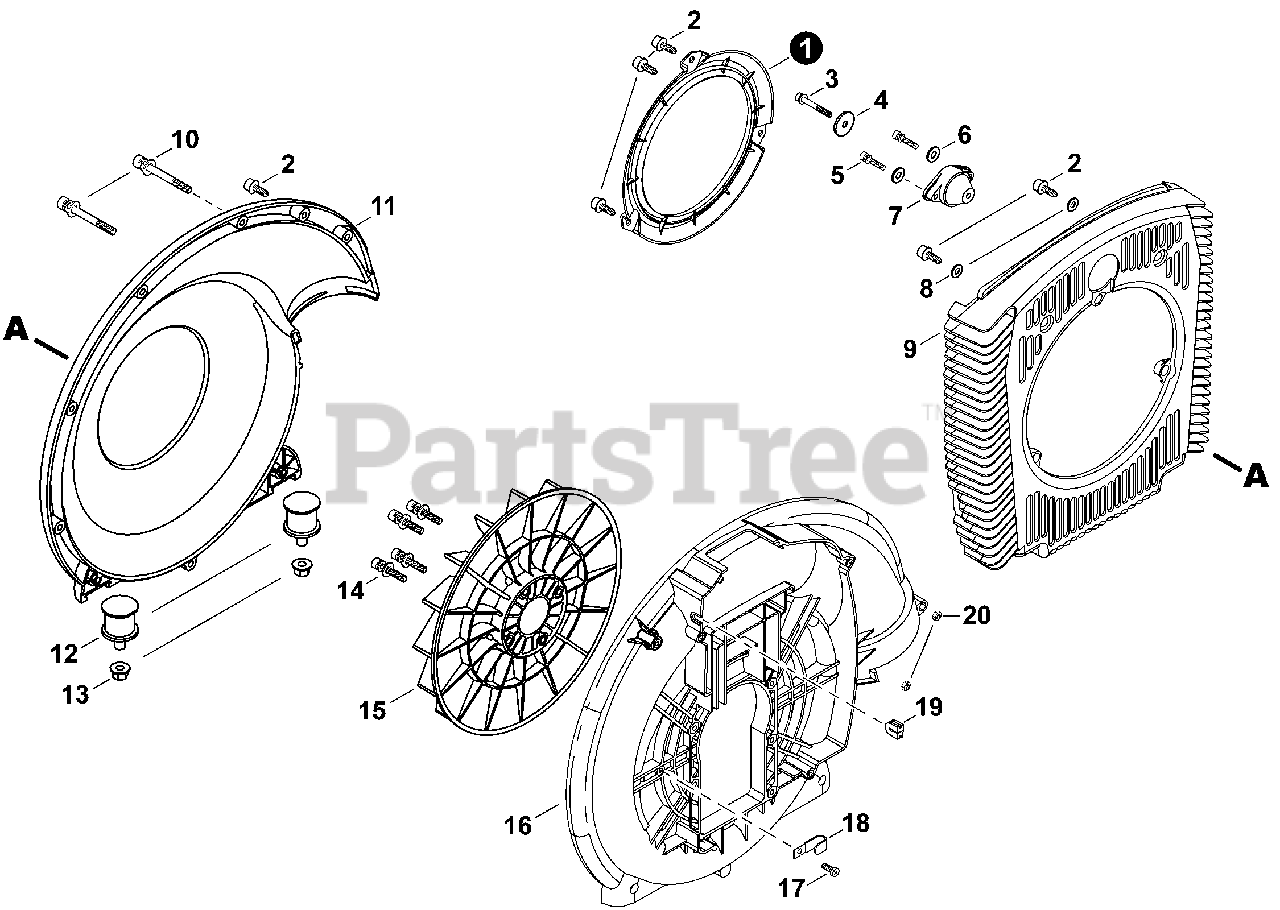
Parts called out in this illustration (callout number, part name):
1	COVER, LEAF GUARD
2	BOLT M5×20
3	BOLT TAPPING M5
4	WASHER Ø25ר5.5×2
5	BOLT 5×16
6	WASHER 5
7	CUSHION, AV 5
8	WASHER 5.5×12×0.8
9	GUARD, LEAF
10	BOLT M5×70
11	COVER, FAN
12	CUSHION, AV 6
13	NUT, FLANGE M6
14	BOLT M6×35
15	FAN Ø257
16	CASE, FAN
17	SCREW, TAPPING 5×14
19	GROMMET
